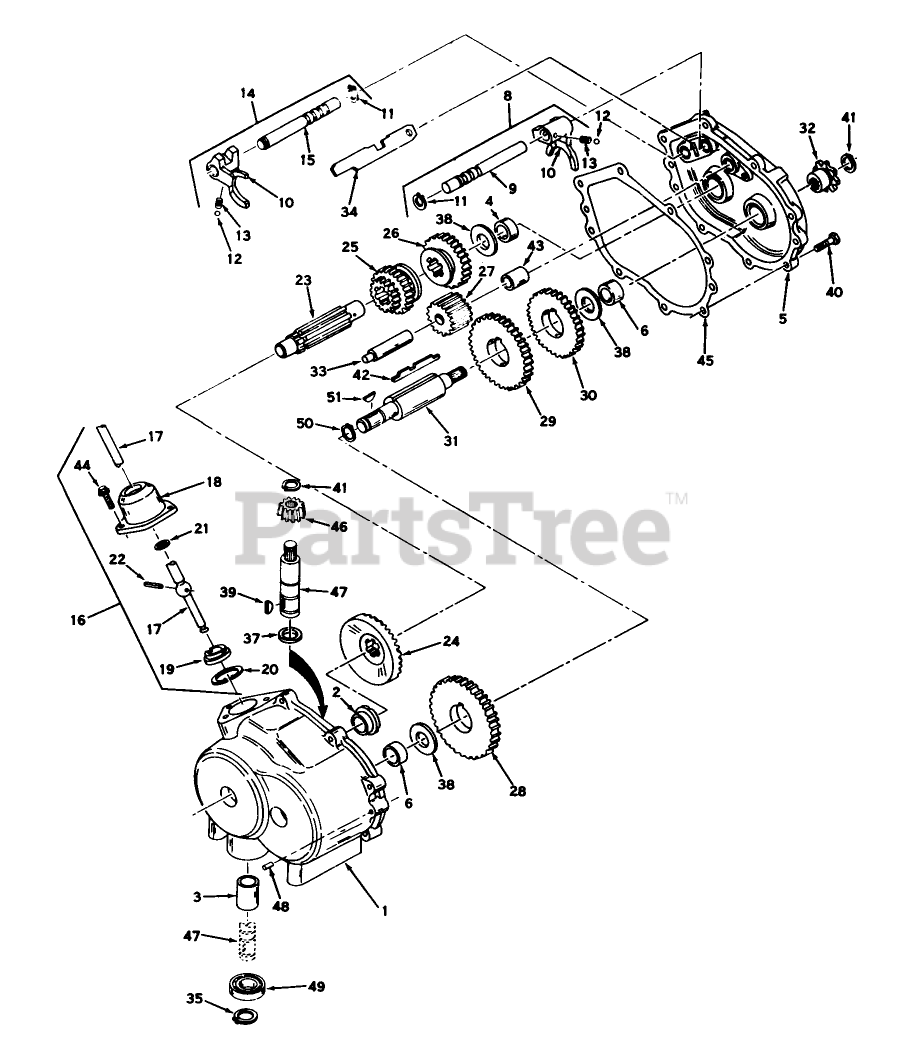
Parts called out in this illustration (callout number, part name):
1	Case Assy., Transmission (Incl. Nos. 2, 3 6)
2	Bearing, Bronze
3	Bearing, Bronze
4	Bearing, Bronze
5	Cover Assembly, Transmission (Incl. Nos. 4 6)
6	Bushing, Bronze
8	Shift Rod Assy (1st and Rev.)(Incl. Nos. 26 thru 30)
9	Shift Rod
10	Shift Fork
11	Ring-Snap
12	Piston ASM
13	Spring
14	Rod Assy., Shift (Incl. Nos. 10 thru 13 15)
15	Rod, Shift
16	Lever Housing Assy., Shift (Incl. Nos. 17 thru 22)
17	Lever, Shift
18	Shift Lever Housing
19	Keeper-Shift Lever
20	Ring-Snap
21	O Ring
22	Roll Pin
23	Shaft, Shifter
24	Gear, Bevel (33 teeth)
25	Gear, Shift 1st 2nd)
26	Gear, Shift 3rd Rev.)
27	Idler, Reverse
28	Gear (39 teeth)
29	Gear (34 teeth)
30	Gear (30 teeth)
31	Shaft, Output
32	Sprocket (8Teeth)
33	Shaft, Reverse Idler
34	Stop, Shifter
35	Ring-Snap
37	Bearing, Thrust
38	Washer
39	Key, Woodruff
40	Screw-Thread Forming
41	Ring-Retainer
42	Key, Countershaft
43	Reverse Idler Spacer
44	Screw
45	Gasket, Transmission
46	Pinion, Input
47	Shaft, Input
48	Dowel Pin
49	Bearing-Ball
50	Snap Ring
51	Kev. Woodruff
